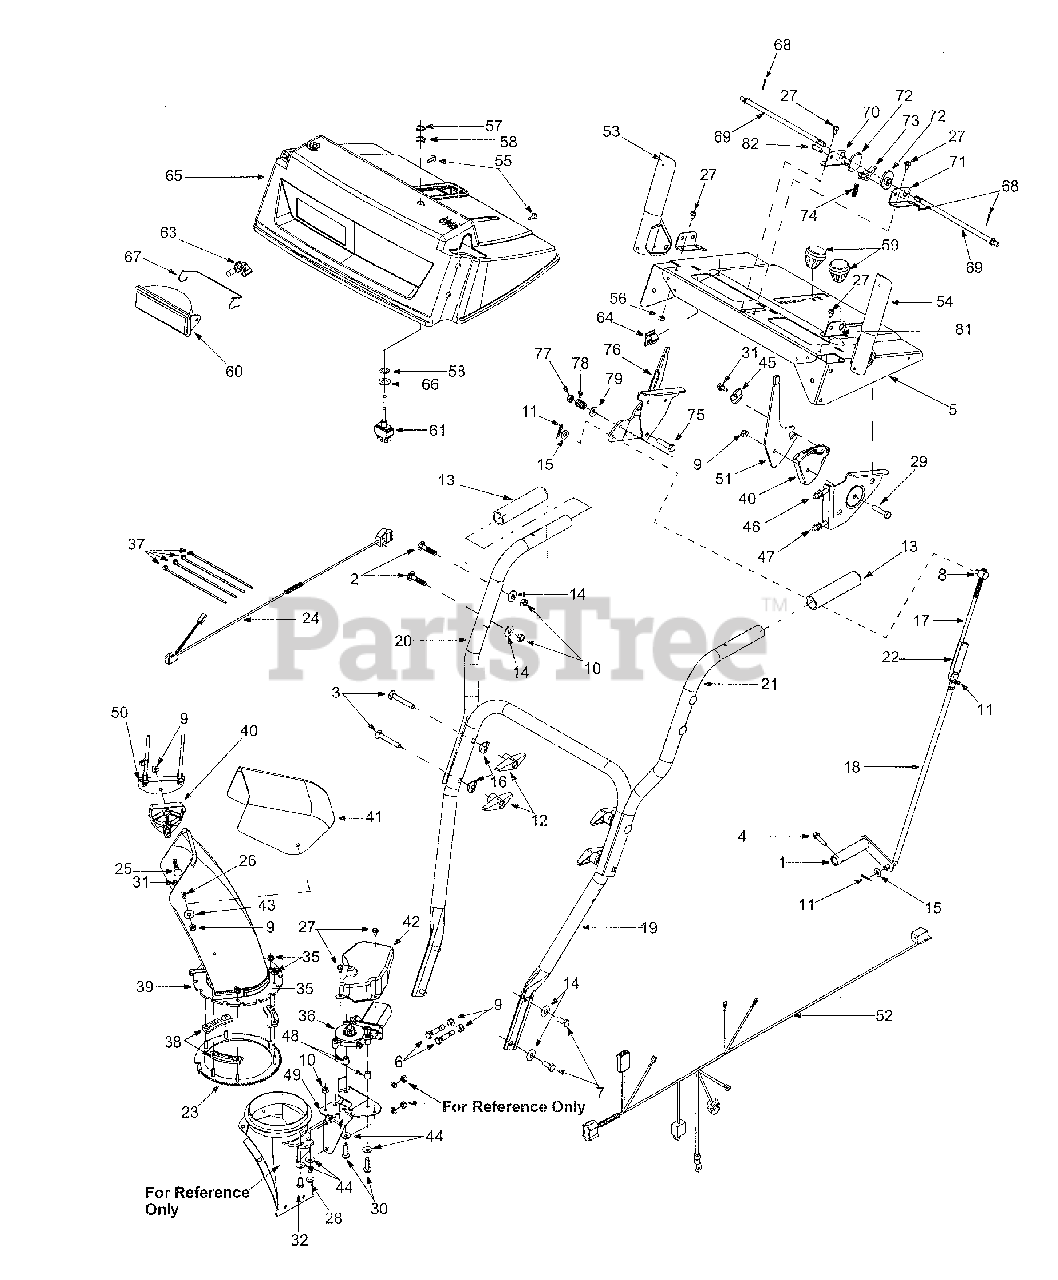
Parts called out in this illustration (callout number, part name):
2	Carriage Bolt 5/16-18 x 1.5"
3	Carriage Bolt 5/16-18 x 2.25"
4	TT Screw 1/4-20 x 1"
6	Shear Bolt 5/16-18 x 1.5"
7	Hex Screw 5/16-18 x .75"
8	Ferrule
9	Hex Lock Nut 5/16-18
10	Hex Nut 5/16-18
14	Belleville Washer
16	Saddle Washer
17	Shift Rod: Upper
18	Shift Rod: Lower
23	Gear Assembly: Ring
24	Electric Harness: Lower
25	Carriage Bolt: 5/16-18 x 1.5"
26	Carriage Bolt: 5/16-18 x .750"
27	TT Screw: 1/4-20 x 0.5"
28	TT Screw: 5/16-18 x 1"
29	Hex Screw: 5/16-1 E3 x 1.5"
30	TT Screw: 5/16-18 x 1.25"
31	Hex Screw AB: 1/4-14 x 0.625"
32	Hex Screw: 5/16-18 x .75"
35	Hex Flange Lock Nut
36	Electric Motor: Chute Crank
38	Chute Flange Keeper
39	Lower Chute
40	Cable Guide: Chute Tilt
41	Upper Chute
42	Motor Cover: Chute: Rotation
44	Belleville Washer
45	Special Washer
46	Control Cable
47	Control Cable
52	Harness Assembly: Upper
53	Handle Assembly RH
54	Handle Assembly LH
55	Special Hex Screw
56	Hex Sems Nut: 1/4-20
58	Lock Ring: Toggle Switch
59	Shift Knob
60	Lamp Housing
61	Toggle Switch: Double Throw
63	Halogen Lamp: 50W, 12V
64	Mounting Clamp
65	Handle Panel
66	Flat Washer
67	Headlight Retainer
68	Cotter Pin .072 x 1.12
72	Cam Handle Lock
73	Handle Lock Pawl
74	Compression Spring: .36 x 1.0
75	Hex Cap Screw: 3/8-24 x 1.5
78	Comp. Spring: .39 x .6 x .88
